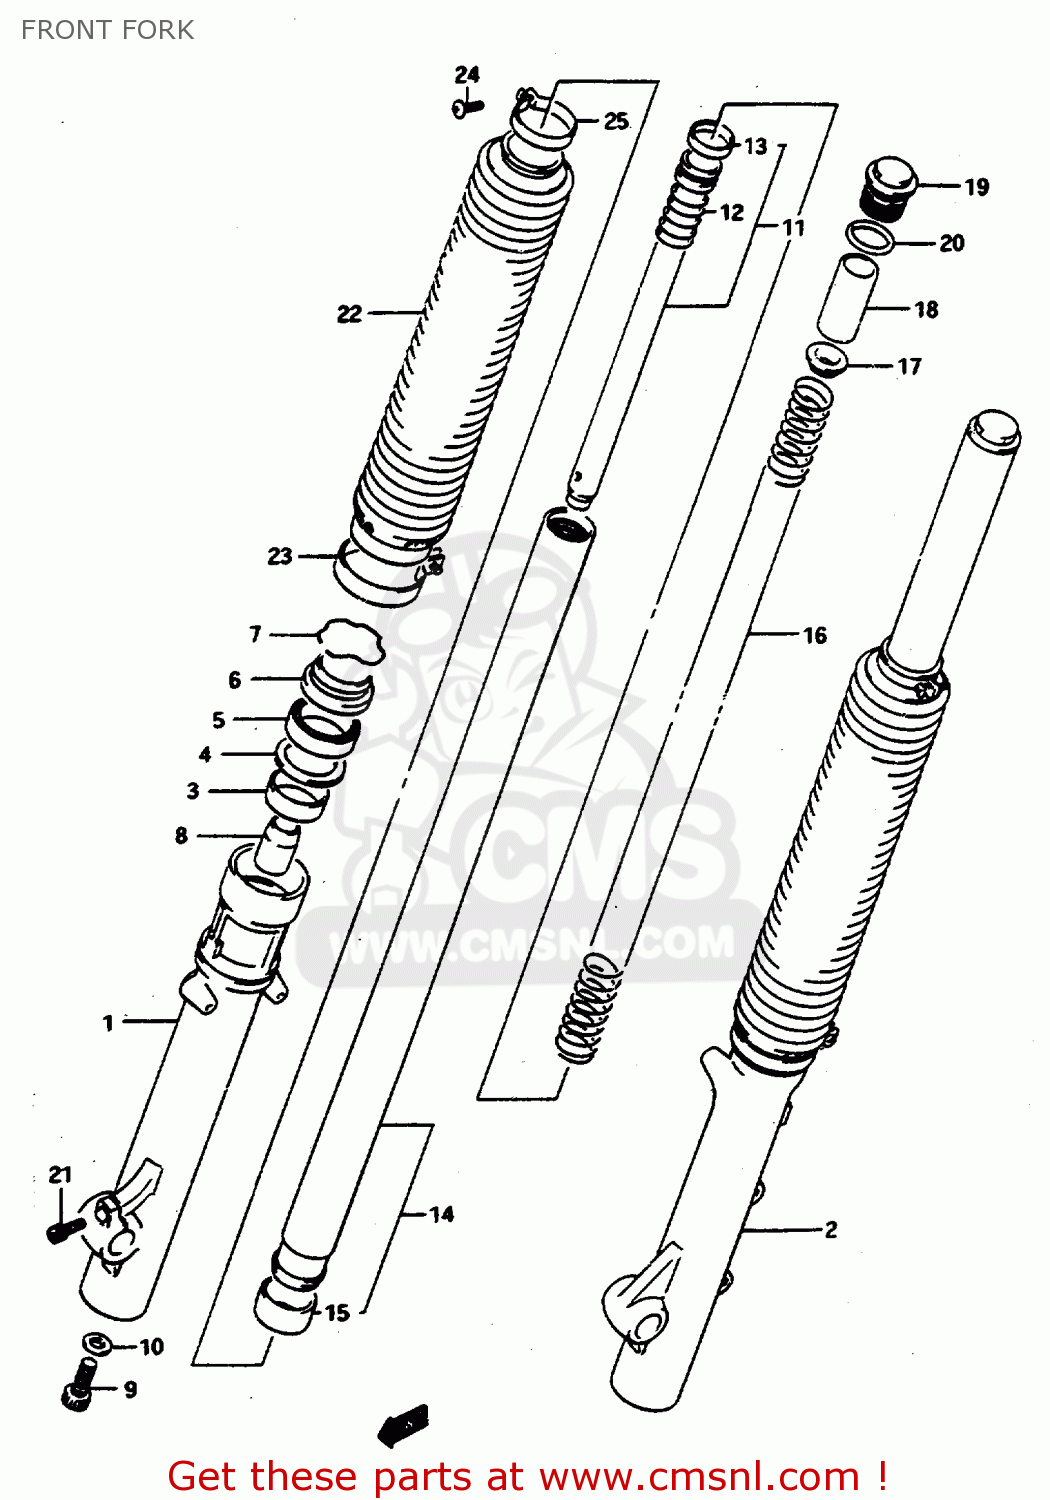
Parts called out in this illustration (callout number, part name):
1	TUBE,OUTER,R
2	TUBE, OUTER LH
3	METAL,SLIDE
4	WASHER
5	SEAL,OIL
6	SEAL,DUST
7	RING,STOPPER
8	PIECE,OIL LOCK
9	BOLT(14X25)
10	GASKET (NAS)
11	CYLINDER
12	SPRING,REBOUND
13	RING,PISTON
14	TUBE,INNER
15	PISTON
16	SPRING
17	GUIDE,SPRING
18	SPACER,FRONT FORK SPRING
19	CAP,FORK
20	O RING
21	BOLT,SOCKET HEAD(8X22)
22	BOOT
23	BAND,BOOT LWR
24	SCREW,BAND BOOT(3.5X10)
25	BAND,BOOT UPR
